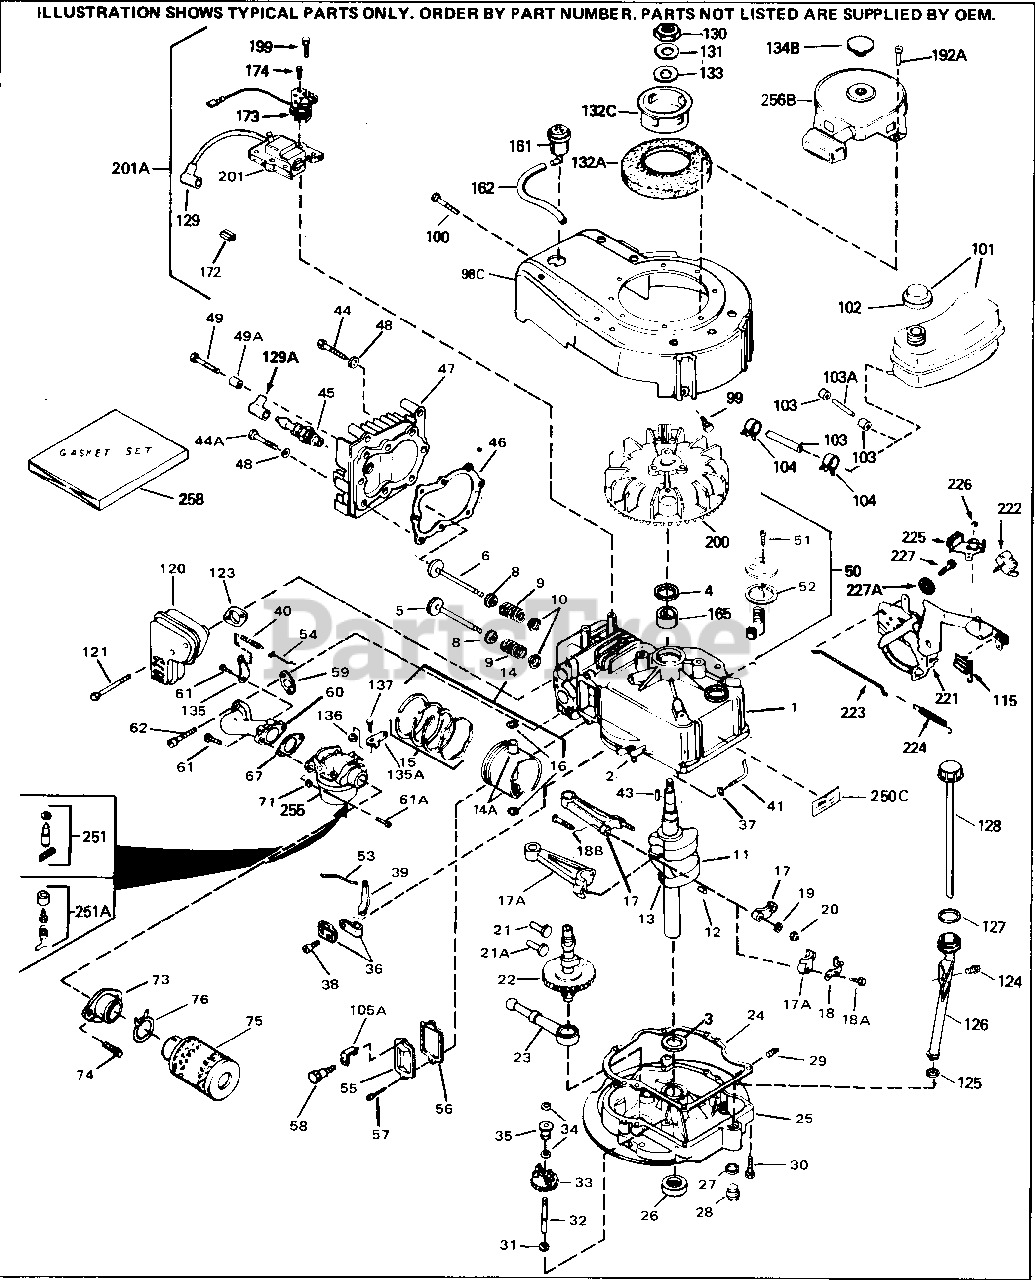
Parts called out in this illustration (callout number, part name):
1	"Cylinder Assy.
2	Pin, Dowel
3	Washer, Thrust
4	Seal, Oil
5	Valve, Exhaust (Standard) (Convention al
5	Valve, Exhaust (1/32" oversize)
6	Valve, Intake (Standard) (Conventiona l
6	Valve, Intake (1/32" oversize) (Conve ntional
8	Cap, Upper valve spring
9	Spring, Valve
10	Cap, Lower valve spring
11	Crankshaft Assy.
12	Pin, Crankshaft gear
13	Gear, Crankshaft
14	Piston, Pin & Ring Assy. (Std.) (2-5/ 8")
14	Piston, Pin & Ring Assy. (.010 oversi ze)
14	Piston, Pin & Ring Assy. (.020 oversi ze)
14A	Piston & Pin Assy. (Std.) (2-5/8")
14A	Piston & Pin Assy. (.010 oversize)
14A	Piston & Pin Assy. (.020 oversize)
15	Ring Set, Piston (Standard) (2-5/8")
15	Ring Set, Piston (.010 oversize)
15	Ring Set, Piston (.020 oversize)
16	Ring, Piston pin retaining
17	Rod Assy., Connecting
18A	Bolt, Connecting rod
21	Lifter, Exhaust valve
21A	Lifter, Intake valve
22	Camshaft (Mech. Compression Release)
23	Pump Assy., Oil
24	Gasket, Mounting flange
25	Flange Assy., Mounting
26	Seal, Oil
27	Gasket, Oil drain plug
28	Plug, Oil drain
30	Screw, Hex hd. Sems, 1/4-20 x 1-1/4
31	Washer, Flat
32	Shaft, Mechanical governor
33	Gear Assy., Governor
34	Ring, Retaining
35	Spool, Governor
36	Clamp, Governor lever
37	Washer, Flat
38	Screw, Hex washer hd., 8-32 x 5/16
39	Lever, Governor
40	Spring, Governor
41	Rod, Governor
43	Key, Flywheel (External Solid State - Gold)
44	Screw, Hex flange hd., 5/16-18 x 2
44A	Screw, Hex flange hd., 5/16-18 x 1-1/ 2
45	Plug, Spark (Champion RJ-19LM or equi valent)
46	Gasket, Cylinder head
47	Head, Cylinder
48	Washer, Flat
50	Breather Assy.
51	Screw, Hex washer hd. self-tap Sems, 10-24 x
52	Gasket, Breather
53	Link, Governor-to-throttle
54	Link, Governor spring
55	Cover, Valve spring box
56	Gasket, Valve spring cover
57	Screw, Fil. hd. Sems, 10-24 x 1/2
59	Gasket, Intake
60	Pipe, Intake
61	Screw, Hex hd., 1/4-28 x 7/8
62	Screw, Hex hd. Sems, 1/4-20 x 1
67	Gasket, Carburetor
71	Nut & Lockwasher, 1/4-28
99	Screw, Hex washer hd. Powerlok thread ,
100	Screw, Hex washer hd. self-tap Sems, 10-24 x
102	Cap, Fuel filler (Red Plastic) (Spurt
102	Cap, Fuel filler (Red Plastic)
102	Cap, Fuel filler (White Plastic) (Sta ndard)
103	Line, Fuel (Braided 8-1/4")
103	Line, Fuel (Braided 16")
103	Line, Fuel (Epichlorohydrin 6-3/4")
104	Clamp, Fuel line
115	Terminal Assy.
121	Screw, Hex hd., 1/4-20 x 2-3/4
124	Screw, Hex washer hd. shakeproof, 10- 32 x
125	Gasket, Oil fill tube
125	"O" Ring (.612 I.D. x .812 O.D. x .10 3
126	Tube Assy., Oil fill (Plastic)
127	"O" Ring
128	Dipstick, Oil (Twist Lock)
129	Cover, Spark plug
130	Nut, Flywheel
131	Washer, Belleville
165	Spacer, Flywheel Key (Solid state)
172	Connector
173	Coil Assy., Alternator
174	Screw, 8-32 X 27/64``
192A	Rivet, Pop (3/16" Dia.)
199	Screw, Hex hd. Sems, 10-24 x 1
200	Flywheel
201	Solid State Assy.
201	Magneto-to-Solid State Conversion Kit
221	Bracket Assy., S.E. Brake
223	Link, Control
224	Spring, Extension
225	Lever, Brake
226	Ring, Retaining
251	Inlet Needle, Seat & Clip Assy.
255	Carburetor
258	Gasket Set
